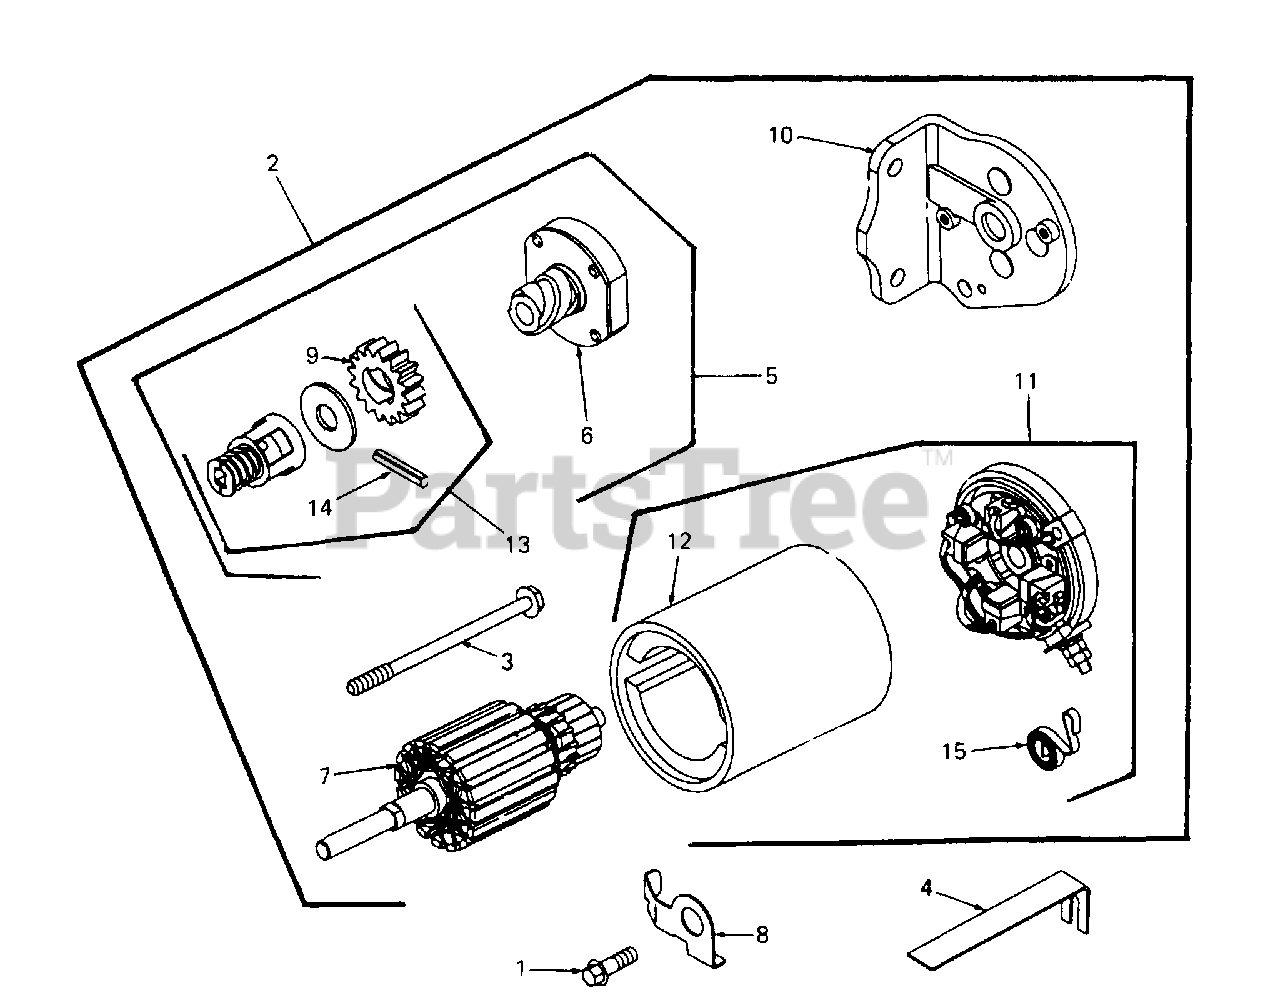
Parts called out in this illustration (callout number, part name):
1	Screw, Hex
2	Motor, Starter Assy
3	Screw, Hex
4	Strap, Starter
5	Starter Drive Group
6	Clutch Assy
7	Armature Assy
8	Clip, Wire
9	Gear, Starter
10	Drive End Cap Assy
11	Cap Assy, Commutator End
12	Housing Assy
13	Kit, Gear
14	Pin, Roll
15	Brush, Spring
